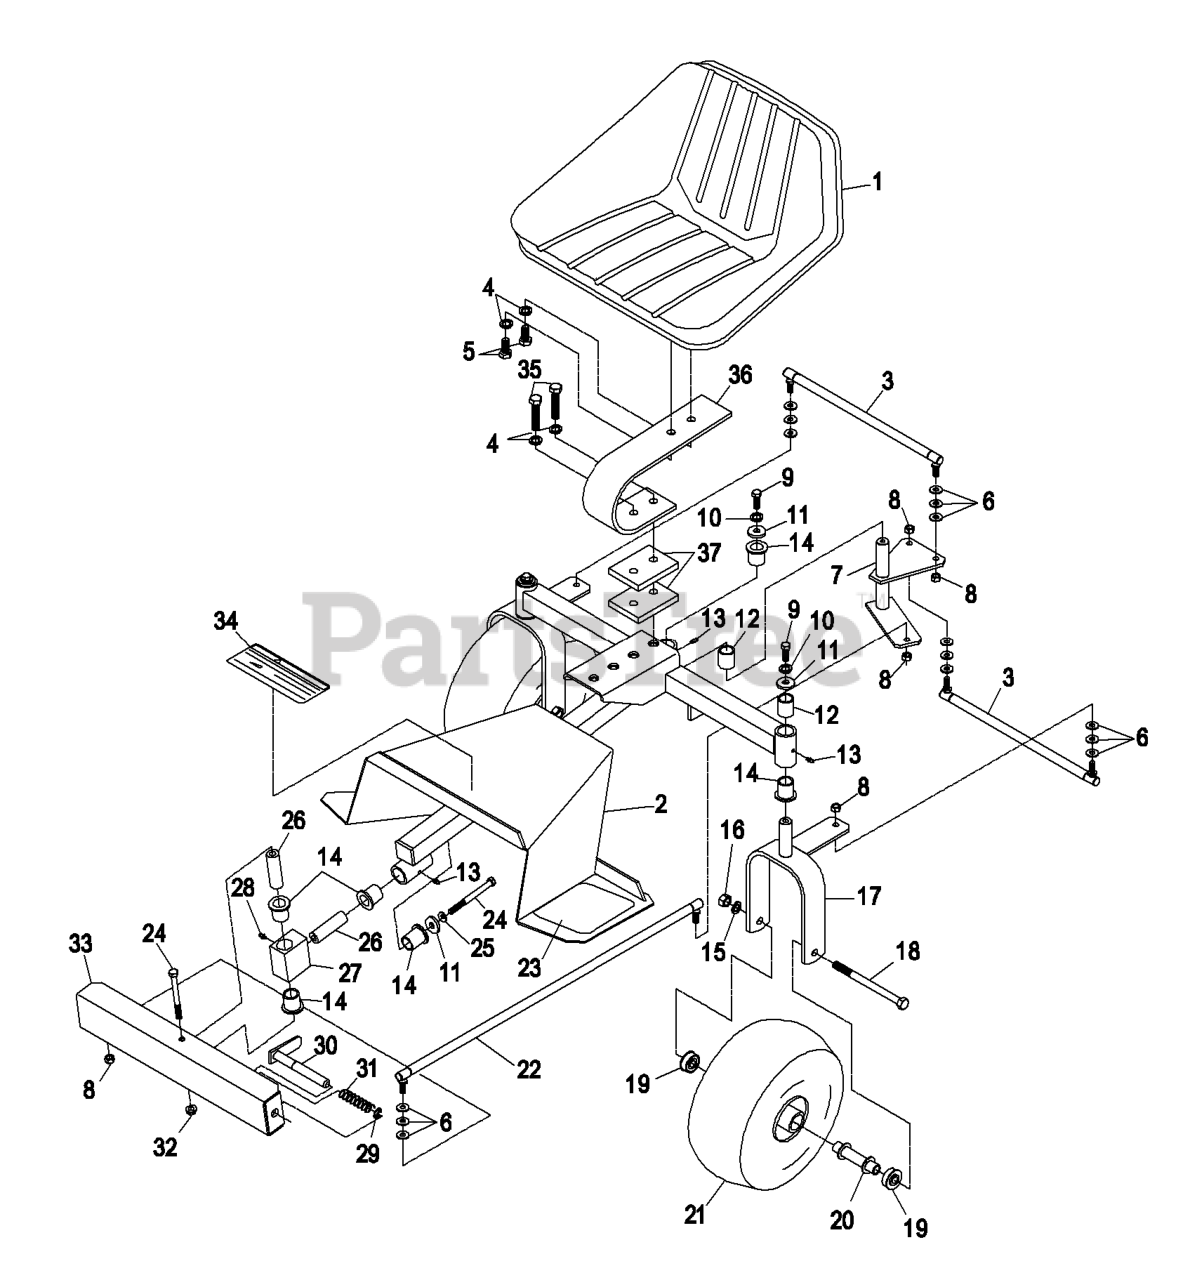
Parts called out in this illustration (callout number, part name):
3	ROD,STABILIZING
4	WASHER-LOCK
5	SCREW-HH
6	WASHER-FLAT
7	WLD,CRANK
9	SCREW-HH
10	WASHER-LOCK
12	BEARING,STRAIGHT
13	FITTING-GREASE
14	BEARING-FLANGED
15	WASHER-LOCK
16	NUT-HH
17	WLD,WHEEL SUPPORT
18	SCREW-HH
20	WLD,WHEEL SPACER
22	ROD-STEERING
23	PAD,ANTI SKID
24	SCREW-HH
25	WASHER-BELLEVILLE
26	PIN,CONNECTING
27	ASM,MOUNTING SWIVEL
28	FITTING-GREASE
31	SPRING,HITCH RELEASE
32	NUT-HHF, WHIZ
33	WLD,HITCH
35	SCREW-HH
36	SPRING,SULKY SEAT
